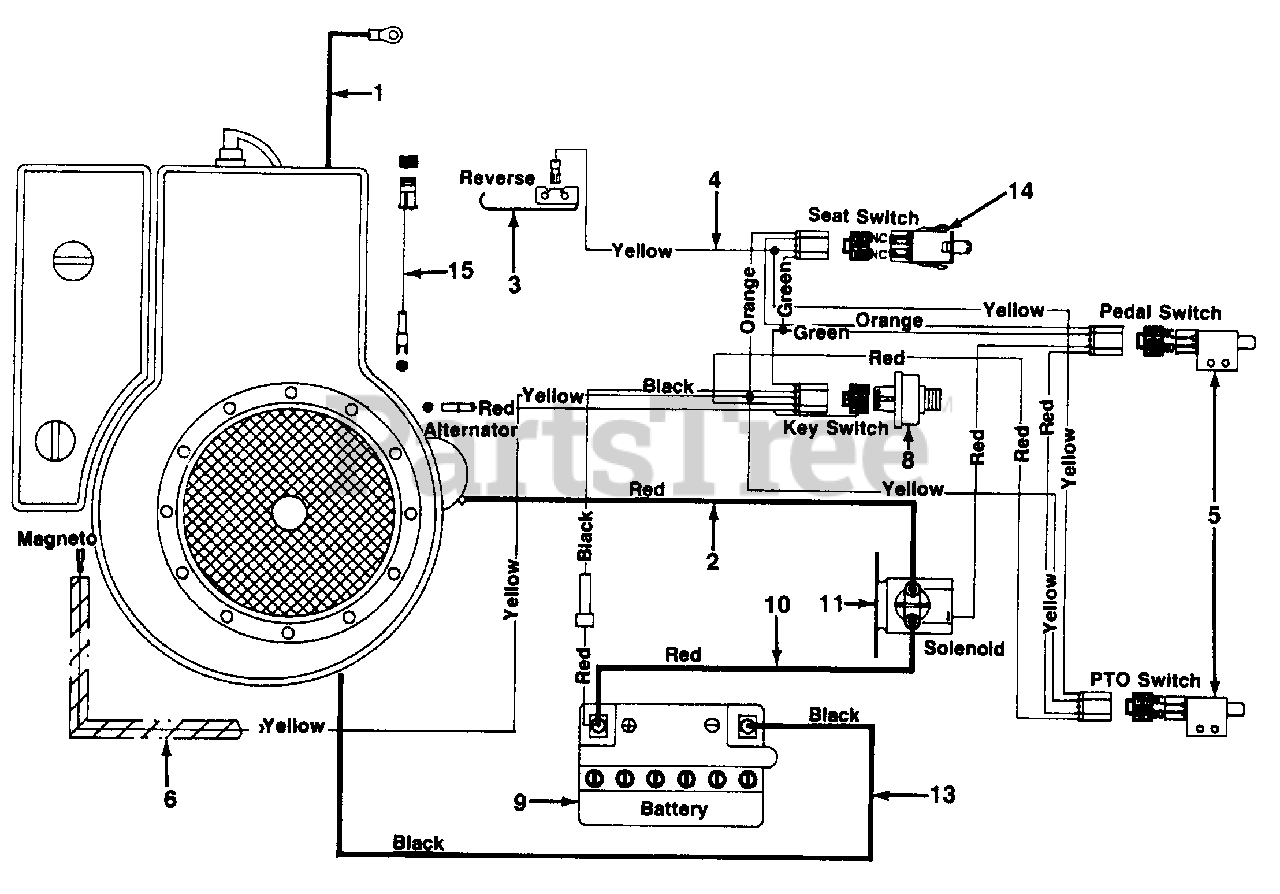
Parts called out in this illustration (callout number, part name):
1	Elec. Wire 8 Ga. x 9.0" Lg.
2	Elec. Wire
3	Spring Switch-Reverse
4	Wire Harness
5	Safety Switch
6	Convoluted Tubing 29" Lg.
8	Ignition Switch
9	Battery 12V
10	Elec. Wire Red w/Boot
11	Solenoid
13	Elec. Wire 8 Ga. x 9.0" Lg.
14	Seat Switch
15	Adapter Harness
